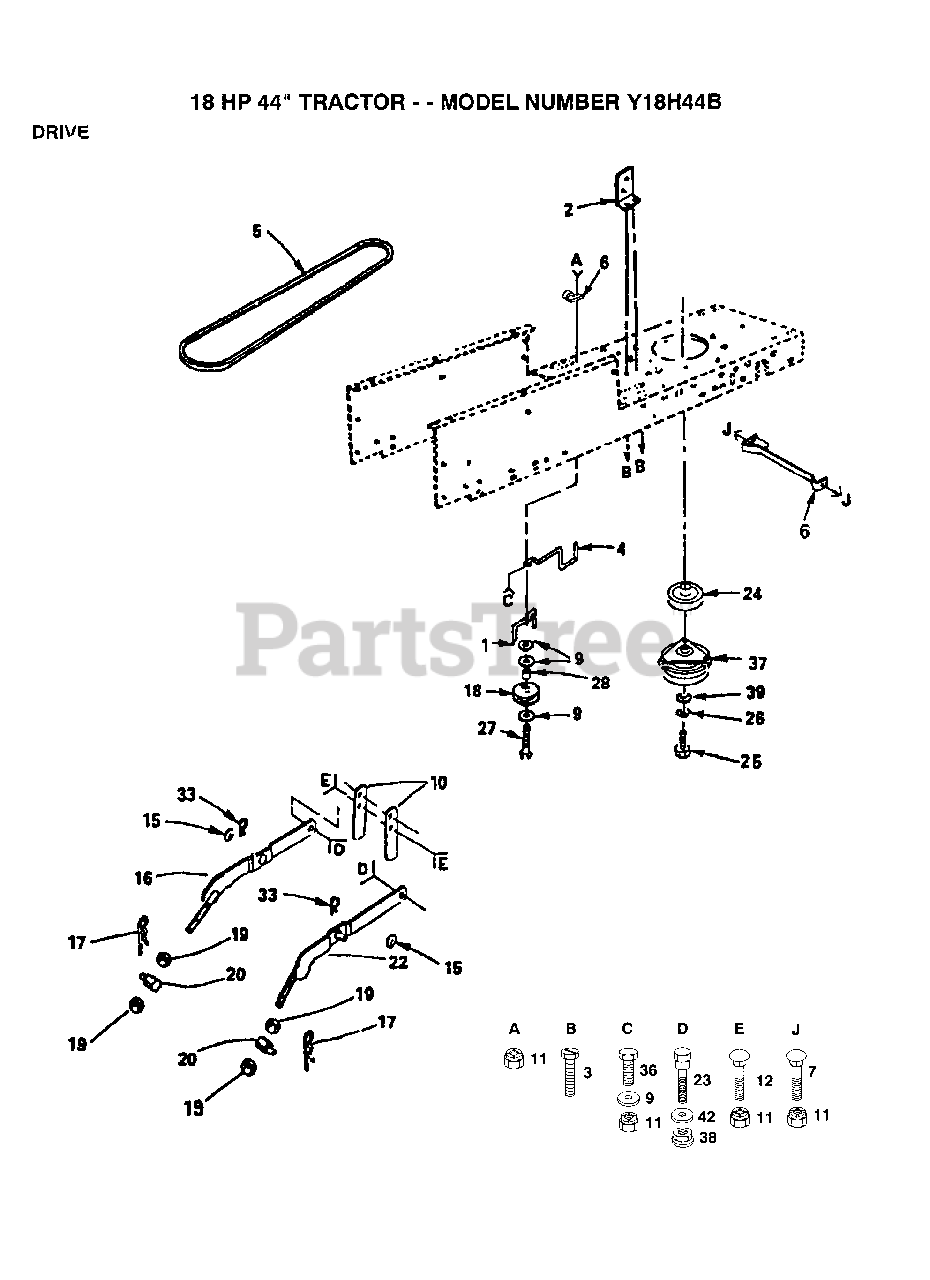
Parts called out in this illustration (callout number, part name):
1	BELT KEEPER LT
2	BRACKET LT
3	SCREW
4	KEEPER.BELT.ENG.L
7	BOLT
9	WASHER
10	UPSTOP
16	LH SUSP ARM ASM
17	SPRING H
18	PULLEY.IDLER.FLAT
19	NUT
22	RH SUSP ARM ASM
23	"BOLT, SHOULDER LT"
26	LOCKWASHER
27	BOLT
28	SPACER T
33	SPRING.RETAINER
36	BOLT
38	NUT SPECIAL T
39	WASHER
42	WASHER T
